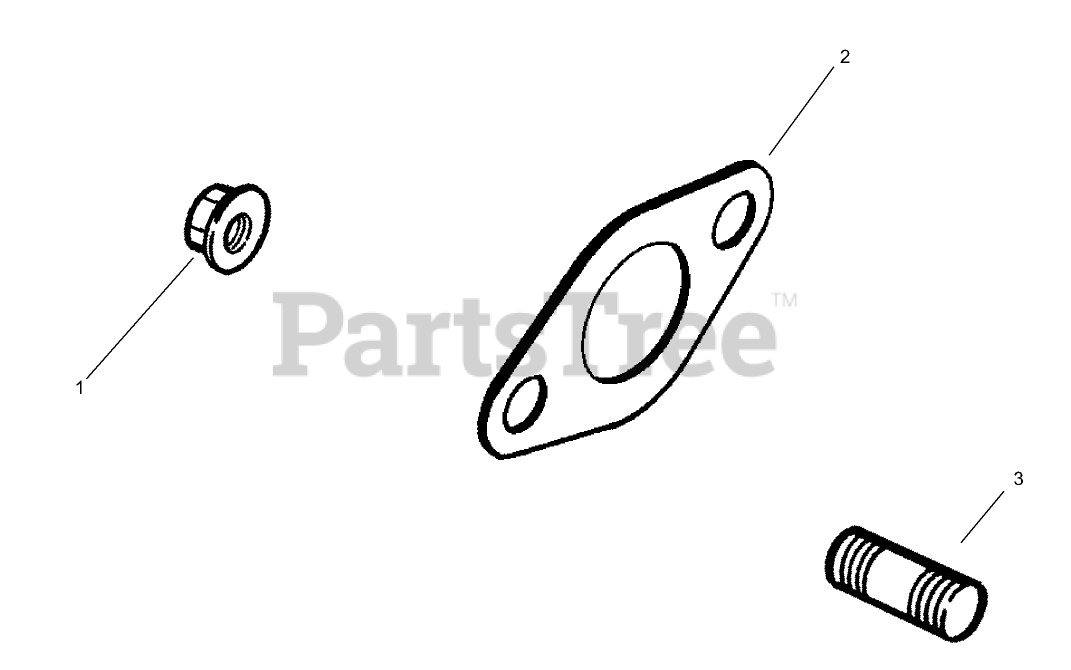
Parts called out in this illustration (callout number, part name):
1	NUT-FLANGE (M8X1.25)
2	Gasket-Exhaust
3	STUD (M8X1.25X33)
